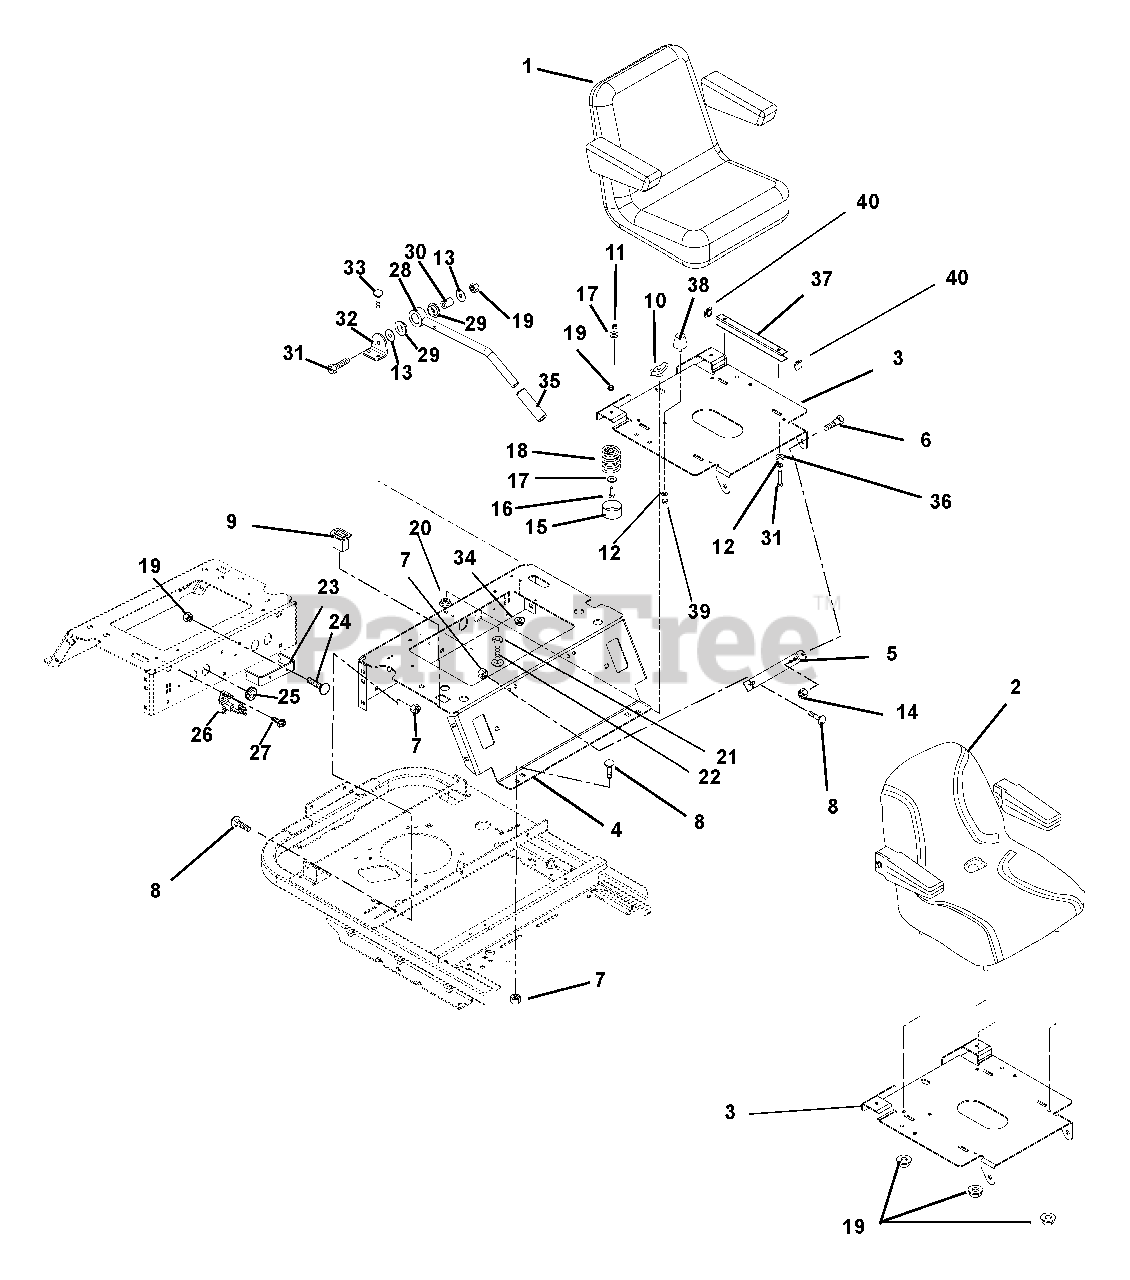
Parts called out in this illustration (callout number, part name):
1	SEAT,V-2505 MICHIGAN W/ARM
2	ASSM, SEAT W/REPLA ARMRESTS
2	KIT, COMPLETE ARMREST
3	BRACKET, SEAT PLATE
4	SEAT SUPPORT
5	BRACKET, SEAT PLATE
6	BOLT-SHLDR .375-16X.150
7	@NUT-LK-NYL-FLG .38-16 YWZC
8	@BLT-RDHDSQNK .38-16X1.00 G5YZ
9	HOUR METER - DIGITAL
9	PLUG, HOUR METER
10	KNOB - WING .312-18 UNC
11	@NUT-LK-NYL .312-18 YWZC
12	@WSHR-LK .31X.078 REG YWZC
13	WSHR-FL-STL .347X1.254X.048YWZ
14	@NUT-LK-TOP-FLG .38-16 YWZC
15	HUB CAP
16	@BLT-HEX .31-18X1.00 GR5 YWZC
17	WSHR-FL-STL .328X1.0X.094 YWZC
18	SPRING, SEAT
19	@NUT-LK-NYL-FLG .31-18 YWZC
20	@NUT-SPNLK-FLG .312-18 YWZC
21	WSHR-FL-STL .505X1.00X.062YWZC
22	BLT-RDHDSQSHNK.31-18X2.75G2YWZ
23	BRAKE ROD SUPPORT
24	@BLT-RDHDSQNK .31-18X1.00 G5YZ
25	GROMMET 1.0ID X 1.38 OD
26	SOLENOID
27	@SCR-TAP .25-20X.37 HWH YWZ TR
28	WMT, PARK BRAKE
29	BSHG-FLG .762X1.48X.44 NYL
30	SPACER .328 X .76 X 1.01
31	@BLT-HEX .31-18X1.75 GR5 YWZC
32	BRKT, BRAKE HANDLE PIVOT
33	@BLT-RDHDSQNK .25-20X.75 G5YZ
34	@NUT-LK-TOP-FLG .25-20 YWZC
36	WSHR-FL-STL .328X.87X.179 YWZC
37	SPACER, SEAT (LOW BACK)
38	BUMPER, RUBBER CONE,STUD MOUNT
39	@NUT-SPNLK-FLG .312-24 YWZC
40	CAPLUG SQR 1-14-20
